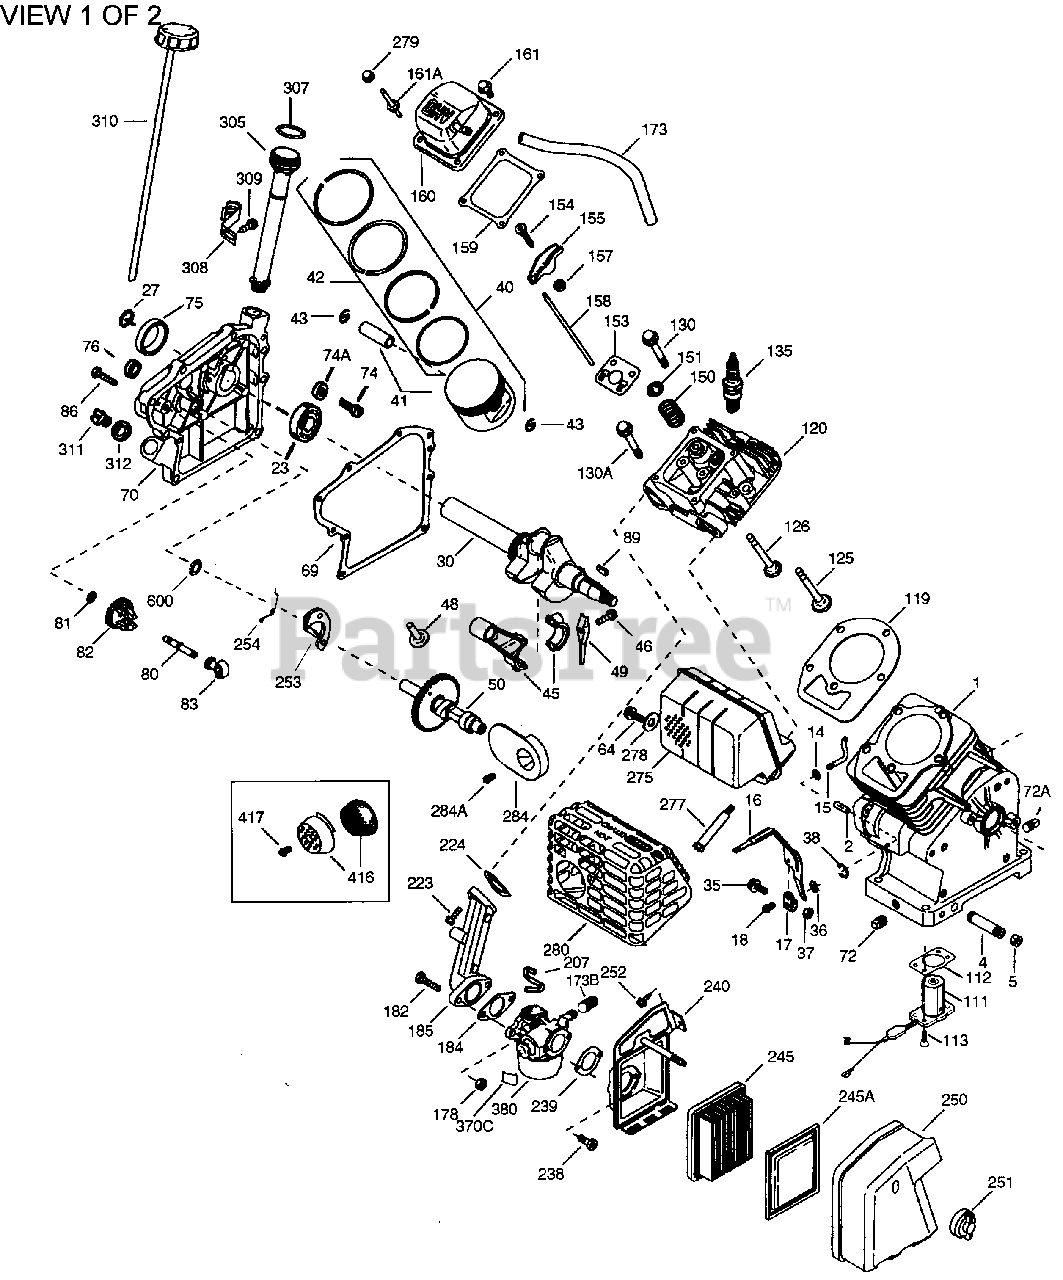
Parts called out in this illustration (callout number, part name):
1	"Cylinder (Incl. 2, 20 & 72)
2	Dowel Pin
14	Flat Washer
15	Governor Rod
16	Governor Lever
17	Governor Lever Clamp
18	Screw, Torx T-15, 8-32 x 3/8"
30	Crankshaft
35	Screw, 10-32 x 3/4"
36	Lock Washer #8
37	Lock Nut, 10-32
38	Retaining Ring
40	Piston, Pin & Ring Set (Std.)
40	Piston, Pin & Ring Set (.010" OS)
41	Piston & Pin Ass'y. (Std.) (Incl. 43)
41	Piston & Pin Ass'y. (.010" OS) Incl. 43
42	Ring Set (Std.)
42	Ring Set (.010" OS)
43	Piston Pin Retaining Ring
45	Connecting Rod Ass'y. (Incl. 46 & 49)
46	Connecting Rod Bolt
48	Valve Lifter
49	Oil Dipper
50	Camshaft (Machined)
64	Screw, 1/4-20 x 5/8"
69	* Cylinder Cover Gasket
70	Cylinder Cover Incl. 75 thru 83 & 311
72	Oil Drain Plug (Sq. hd., 1/4-18)
75	Oil Seal
80	Governor Shaft
82	Governor Gear Ass'y. (Incl. 81)
83	Governor Spool
86	Screw, 1/4-20 x 1-1/4"
89	Flywheel Key (also available in Packa ged Part #740007B)
119	* Cylinder Head Gasket
120	Cylinder Head
125	Exhaust Valve (Std.) (Incl. 151)
125	Exhaust Valve (1/32" OS) (Incl. 151)
126	Exhaust Valve (1/32" OS) (Incl. 151)
126	Intake Valve (Std.) (Incl. 151 & 151A )
130	Screw, 5/16-18 x 1-1/2"
130A	Screw, 5/16-18 x 2-41/64"
135	Resistor Spark Plug (RN4C) also avail able in Packaged Part #740069
150	Valve Spring
151	Valve Spring Cap
153	Push Rod Guide
154	Rocker Arm Stud
155	Rocker Arm
157	Nut, 1/4-28
158	Push Rod
159	* Rocker Arm Cover Gasket
160	Rocker Arm Cover
161	Screw, 1/4-20 x 31/64"
173	Breather Tube
178	Nut, 1/4-20
182	Screw, 1/4-20 x 1"
184	* Carburetor To Intake Pipe Gasket
185	Intake Pipe
207	Throttle Link
223	Screw, 1/4-20 x 1"
224	* Intake Pipe Gasket
238	Screw, 10-32 x 1/2"
239	* Air Cleaner Gasket
240	Air Cleaner Body (Incl. 239)
245	Air Filter (Paper) (also available in Packaged Part #740031B for model VLV only) (also available in Packaged Pa rt #740061C for model OH195)
250	Air Cleaner Cover
251	Wing Nut
252	Screw, 10-32 x 1/2"
275	Muffler
277	Screw, 1/4-20 x 2-9/32"
311	Oil Fill Plug (Incl. 312) also availa ble in Packaged Part #740079
380	Carburetor (Incl. 184)
416	Spark Arrestor Kit (Incl. 417) Option al
417	Screw, 8-32 x 3/8"
999	Summer Maintenance Kit (incl. Oil, Sp ark Plug, Air Cleaner, & Ultra Fresh)
